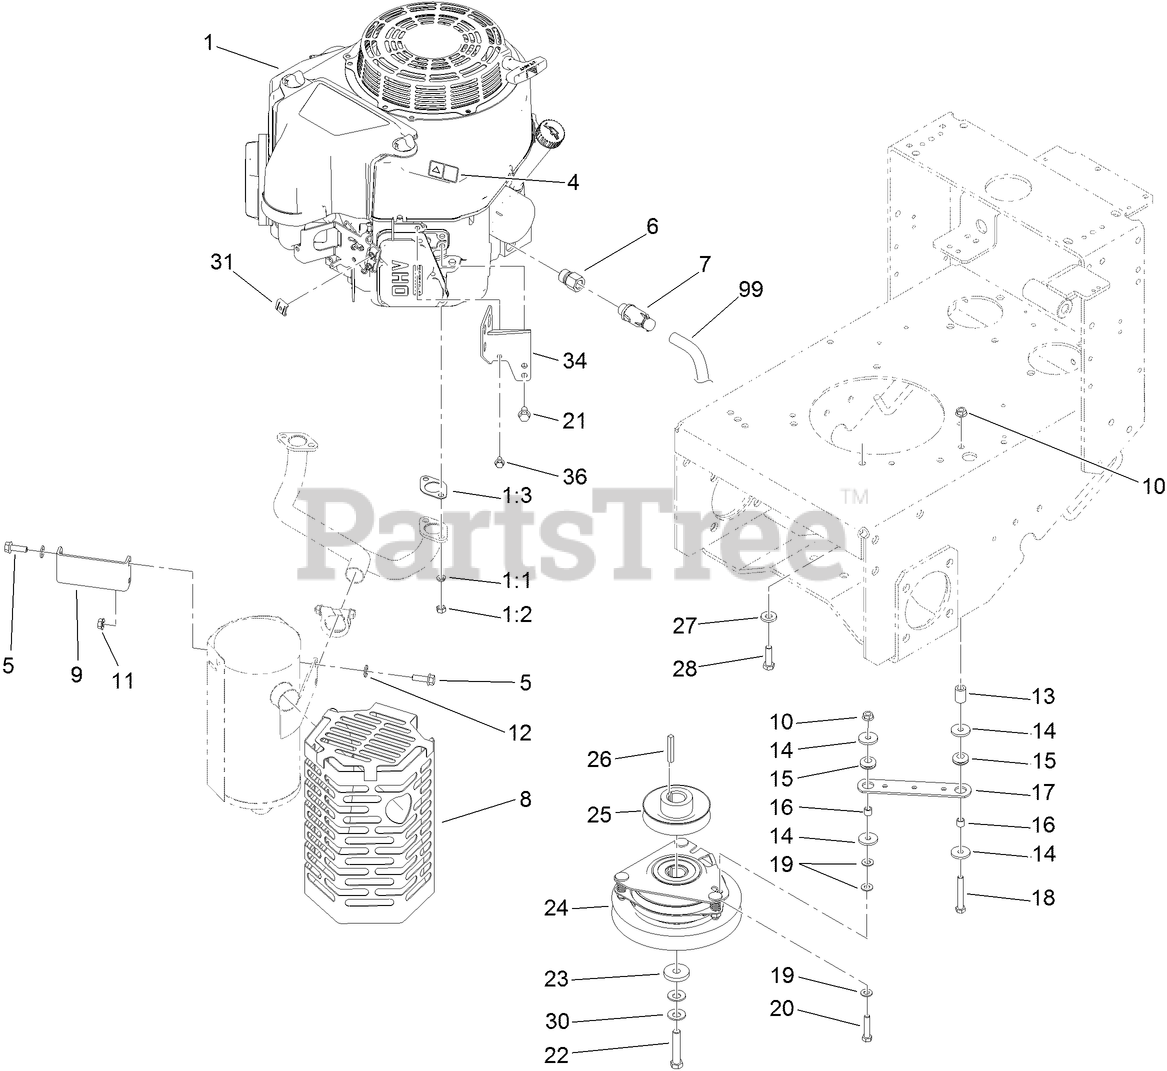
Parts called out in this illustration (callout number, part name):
1:1	WASHER-LOCK
1:3	GASKET-EXHAUST
4	DECAL-WARNING
5	SCREW-HHF
6	Adapter
7	VALVE-DRAIN, OIL
8	SHIELD-MUFFLER
9	BRACKET-SHIELD, MUFFLER
10	NUT-HF
11	NUT-HF, LOCK
12	WASHER-SPRING
13	TUBE-RETAINER
14	WASHER
15	GROMMET
16	SPACER
17	STRAP-CLUTCH, BRAKE
18	SCREW-HH
19	WASHER-PLAIN
20	SCREW-HH
21	SCREW-HHF
22	SCREW-HH
23	WASHER
24	CLUTCH / BRAKE ASM
25	Pulley
26	KEY-SQUARE
27	WASHER-BELLEVILLE
28	SCREW-HH
30	WASHER-SPRING
31	CLAMP-CABLE
34	BRACKET-MUFFLER
36	SCREW-HHF
99	HOSE-DRAIN, OIL
